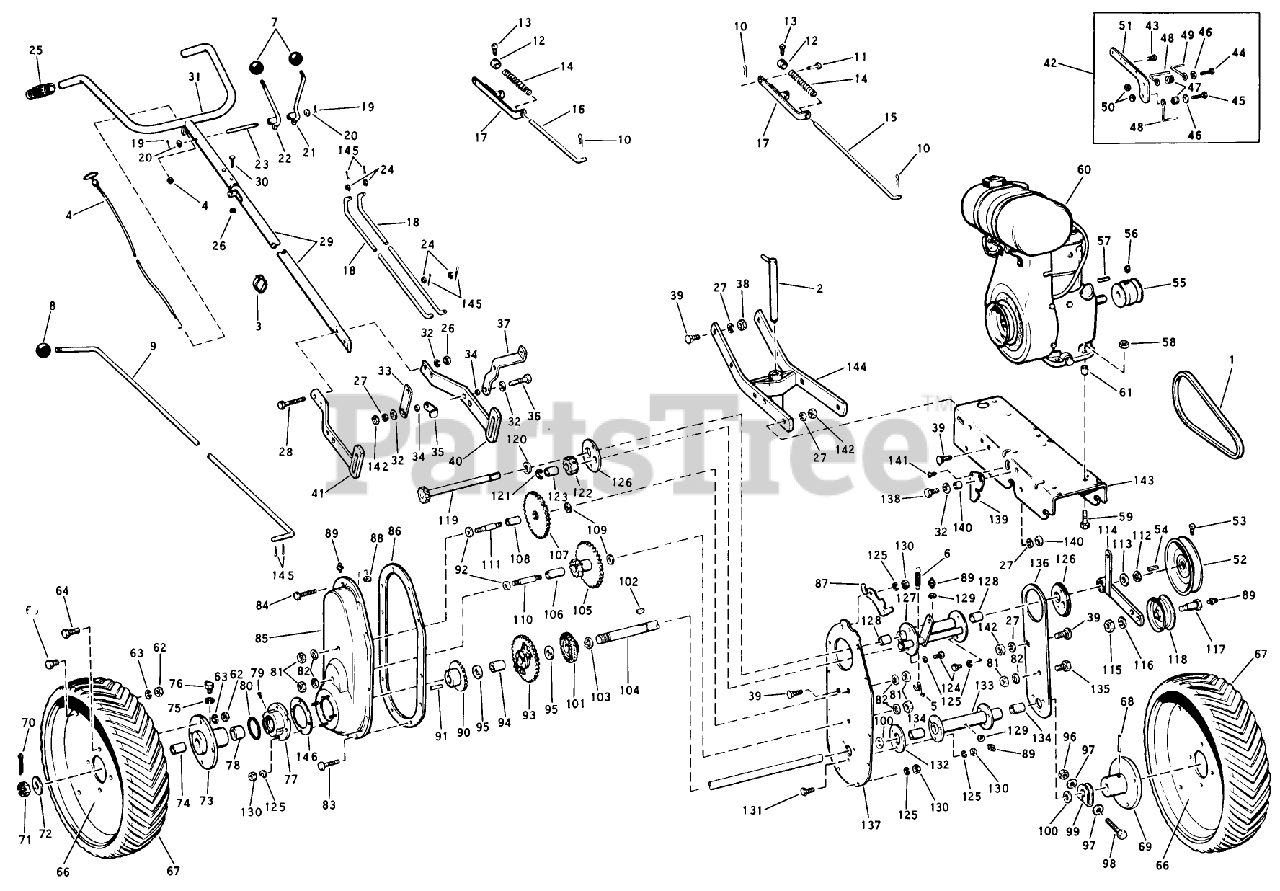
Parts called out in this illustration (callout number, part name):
1	Lockwasher
2	Hitch Pin
5	Bushing
13	Set Screw
16	Trans. Control Spring Rod
17	Spring Bracket
18	TINE LH
19	Cotter Pin
21	Control Handle, L.H.
22	Control Handle, R.H.
28	Hex Capscrew
29	Lower Tube
33	Shifting Lever
36	Hex Capscrew 3/8-16 x 1-1/2 Lg.
38	Hex Nut 3/8-16
39	Carr. Bolt 3/8-16 x 1-1/2 Lg.
40	Handlebar Brkt., L.H.
41	HandlebarBrkt., R.H.
42	Belt Guide Assembly
44	Hex Capscrew 5/16 18 x 1-1/4 Lg.
45	Hex Capscrew 5/16 18 x 1-1/8 Lg.
46	BAR-LIFT LINK *R
52	Pulley Assembly
53	Set Screw
56	Set Screw
58	Nut and Washer
59	Hex Capscrew
62	Hex Nut 5/16-18
64	Hex Capscrew 5/16-18 x 1 Lg.
65	Hex Capscrew 5/16-18 x 5/8 Lg.
69	GEAR 24T
70	Cotter Pin
71	Hex Slotted Nut
73	Right Wheel Hub Assy.
74	Bushing
75	Lockwasher
76	Grease Fimng
77	Flange Bushing Assy.
78	Bushing
79	Grease Fitting
80	Oil Seal
81	Hex Jam Nut 7/16 x 14
83	Hex Capscrew 1/4-20 x 1/2 Lg.
84	Capscrew
85	Gearcase Cover
88	Hex Jam Nut
89	Grease Fitting
91	Rear Wheel
93	Final Drive Gear Dif. Pinion Assembly
94	Bushing
95	Thrust Washer
96	Hex Nut
98	Hex Capscrew
105	Second Intermediate Gear and Pinion Assembly
107	First Inter. Gear Pinion Assy.
108	Bushing (Oilite)
111	First Intermediate Shaft
112	Retaining Ring
114	Idler Pulley Lever
115	Hex Jam Nut
118	Idler Pulley
119	Input Gear
121	Retaining Ring
122	Idler Pinion Assembly
123	Bushing
124	Capscrew
125	Lockwasher 1/4
127	Input Tube Idler Shaft Assy.
129	Lift Bar
130	Hex Nut
131	ASSEMBLY MUFFLER
133	Axle Tube Assembly
134	Bushing
135	Capscrew 7/16-14 x 3/4 Lg.
136	Left Support Plate
137	Back Plate
141	Drive Screw #10 x 3/8 Lg.
145	BUMPER-RUBBER
146	Flange Bushing Gasket
